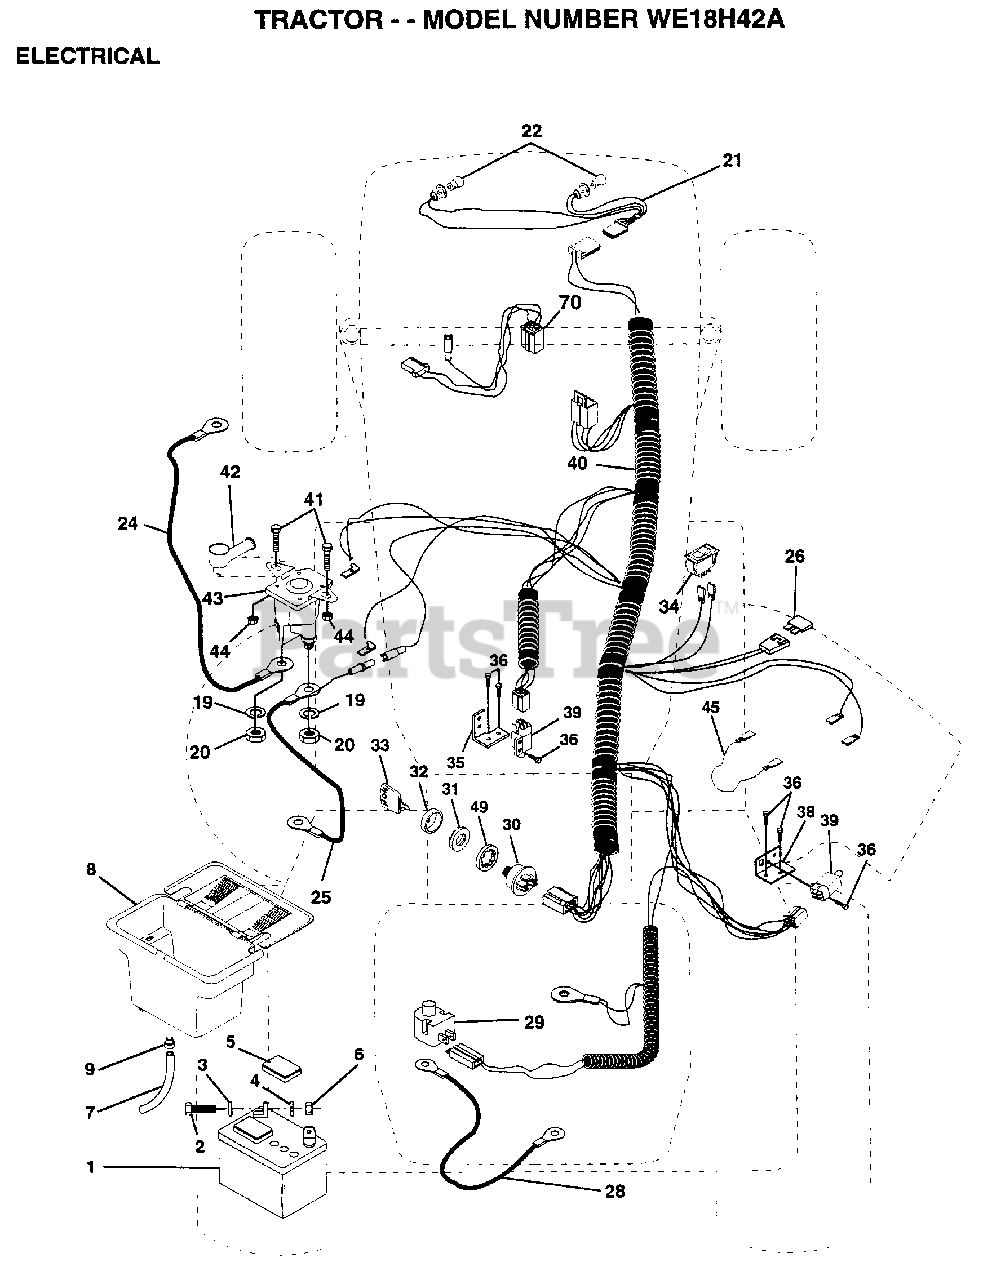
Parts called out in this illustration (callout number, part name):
2	BOLT LT
3	WASHER
4	LOCKWASHER
5	"CAP,BATTERY "
7	TUBE T
9	HOSE CLAMP T
20	NUT
21	"HARNESS,LIGHT SOC"
22	HEADLAMP BULB
24	"CABLE T, BATTERY"
25	CABLE.BTRY.6GA.38
26	FUSE HYT
28	CABLE T
29	SWITCH SEAT
32	COVER KEY SWITCH
33	KEY MLD GEN DELTA
34	SWITCH LT
35	BRACKET LT
36	SCREW
38	BRACKET SWITCH IN
39	SWITCH INTERLOCKT
40	HARNESS.IGN.DASH.
41	BOLT HXHD FIN
44	NUT HXKEP 1/4X20
45	ADAPTER AMMETER
49	LOCKWASHER
70	HARNESS ENG DUAL
